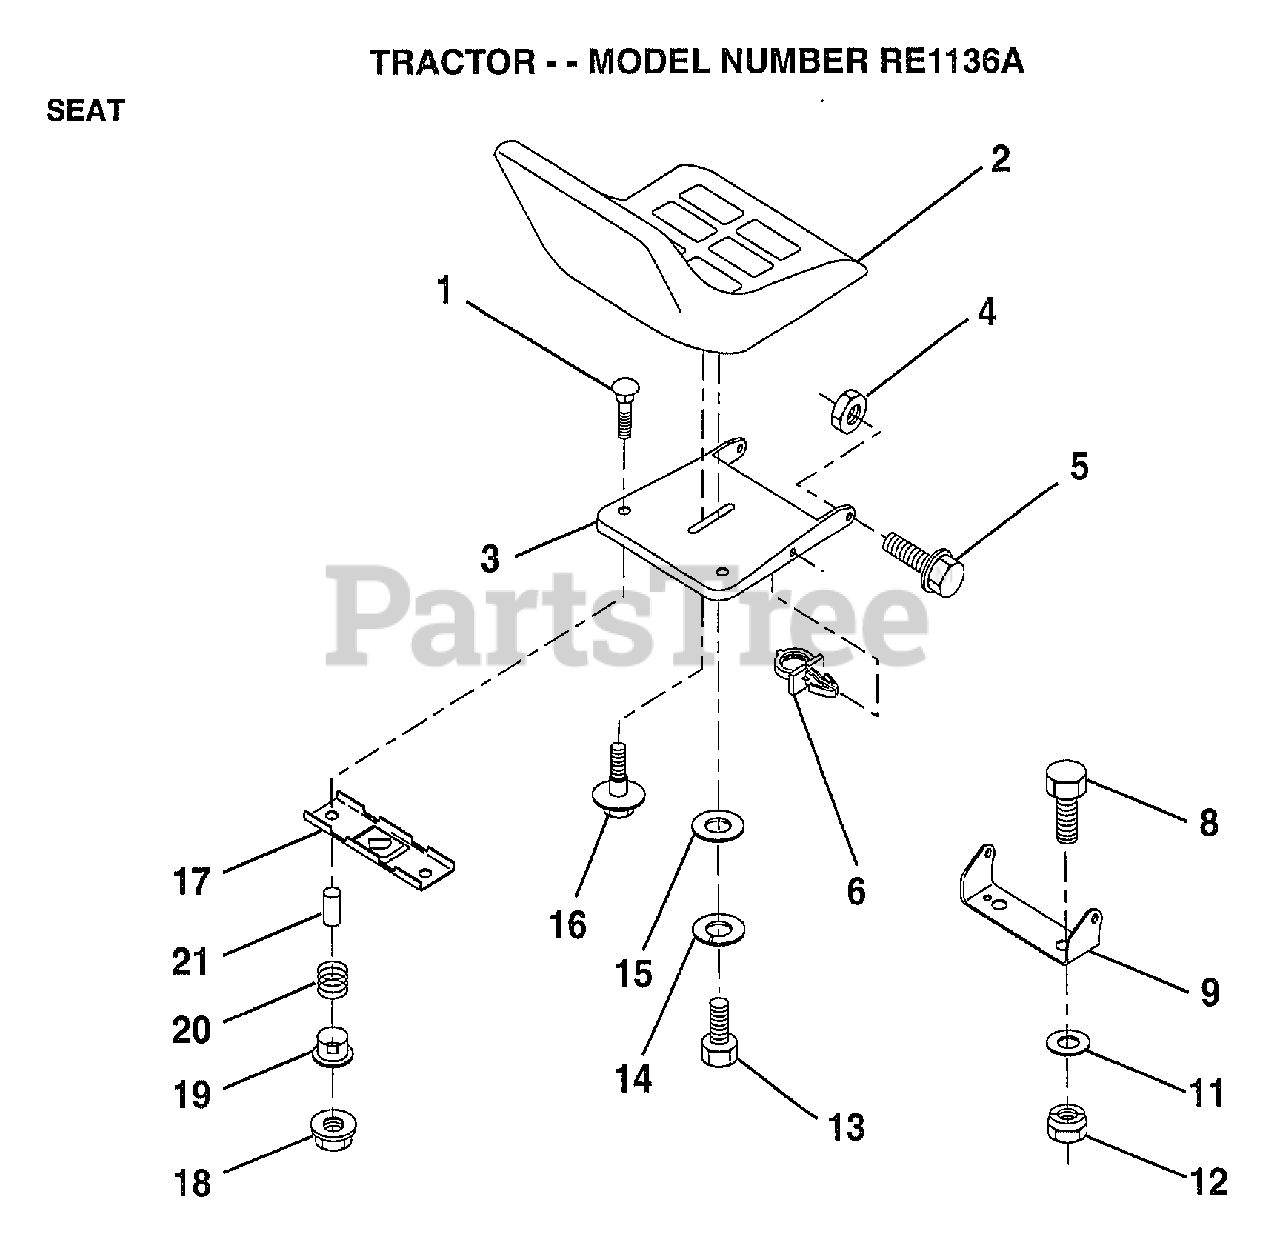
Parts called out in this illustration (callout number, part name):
1	BOLT-RD HD SQ NK
3	PAN-SEAT
4	NUT
5	"BOLT,SHOULDER"
6	CLIP.PUSH-IN.HING
8	BOLT
9	BRACKET PVT SEAT
11	WASHER
12	NUT
13	BOLT
14	LOCKWASHER
15	WASHER
16	"BOLT,SHOULDER"
17	BRKT SWITCH
19	BUSHING
20	SPRING
21	SPLIT SPACER
